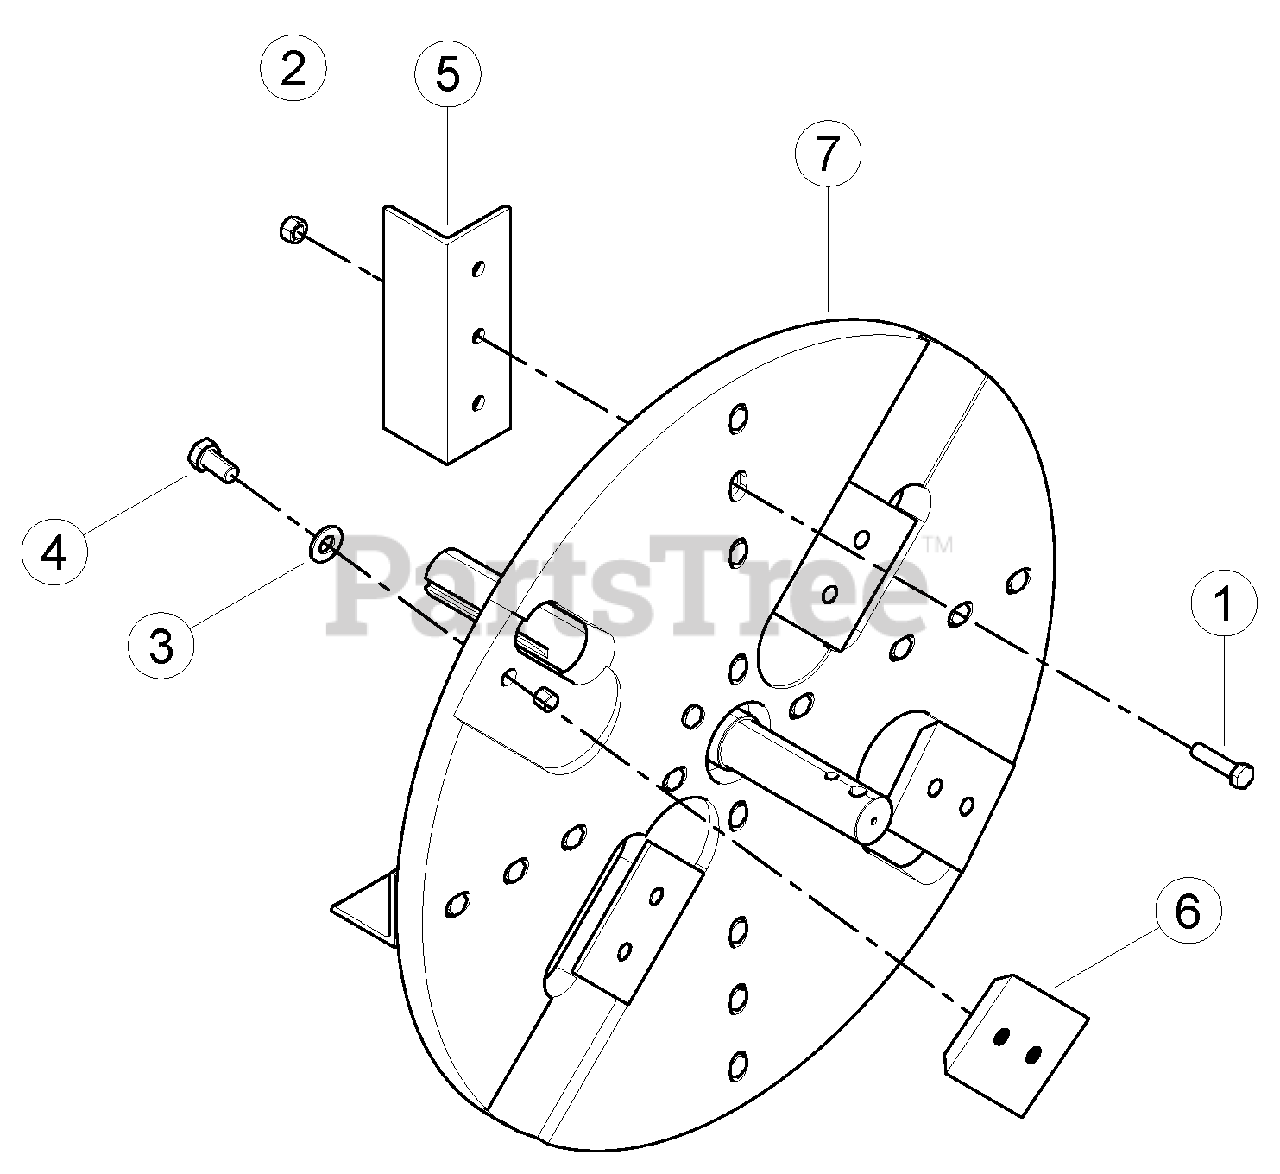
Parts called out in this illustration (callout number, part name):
1	BOLT, 1/2 X 2 HEX HD GR5 ZP
2	NUT, 1/2 CENTERLOCK GRB ZP
3	WASHER, 5/8 SAE HARDENED
4	BOLT, M16 X 2.0 X 30 HEX HD W/PATCH
5	PADDLE, BIG CHIPPER
6	BLADE, BIG CHIPPER (FOR SERVICE ORDER KIT #76293-00, CHIPPER BLADE REPLACEMENT)
6	KIT, CHIPPER BLADE
7	ASSEMBLY, 9 INCH CHIPPER DISK
